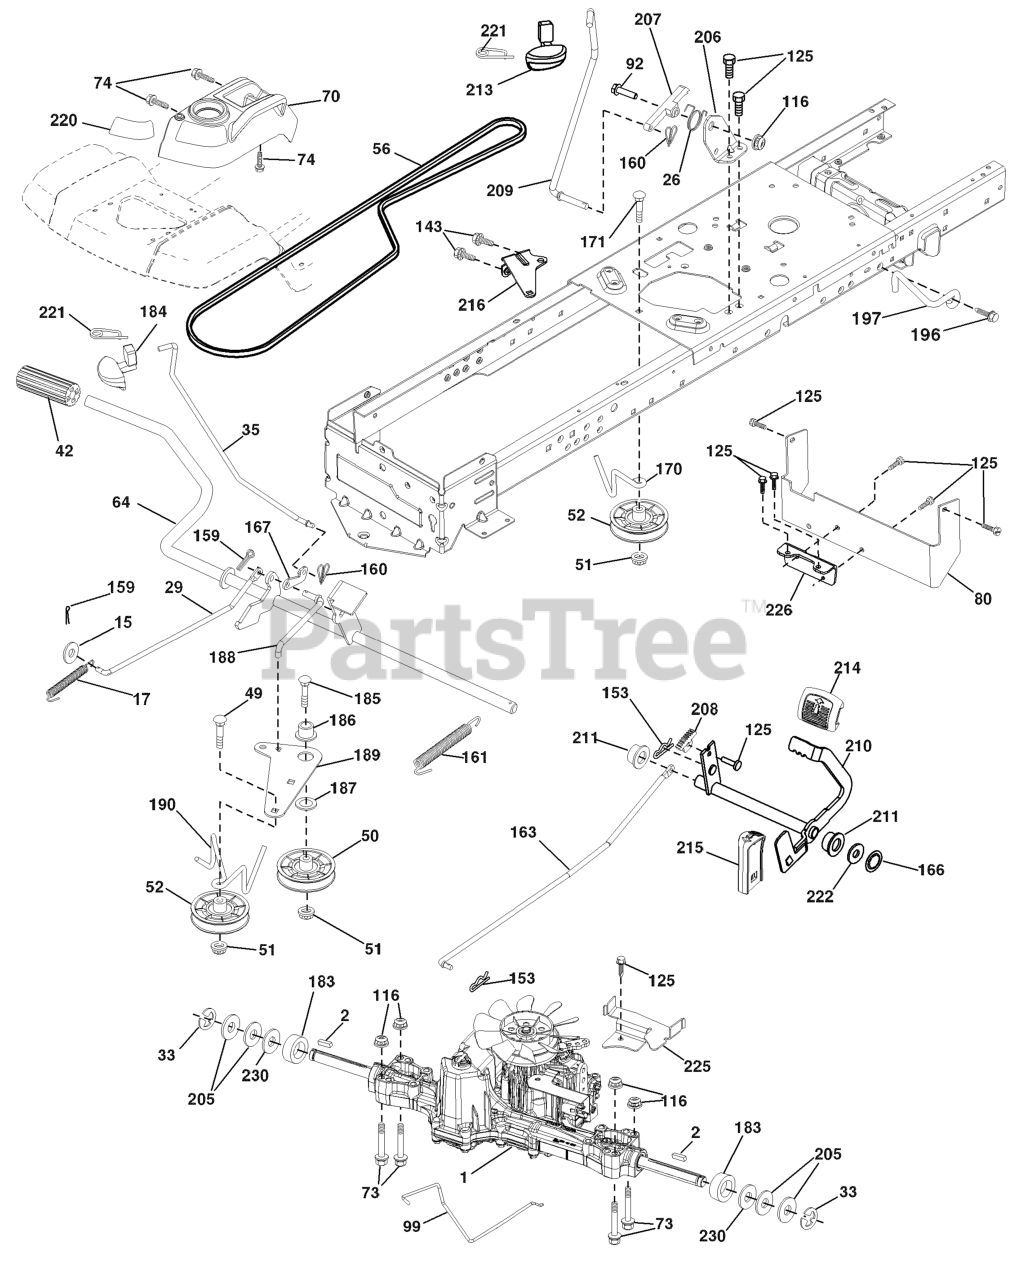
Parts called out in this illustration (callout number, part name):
1	TRANSAXLE.K46CR.ETC.20'PCH.TLT
2	SQUARE KEY
15	WASHER
17	SPRING.BRAKE.K46.GREEN
26	SPRING.RETURN.CRUISE
29	ROD.BRAKE.K46
35	ROD.BRAKE.PARKING.GT.H
42	PEDAL COVER T
50	IDLER.FLAT.910.OFFSET
51	NUT LOCK FLG 3/8-16 UNC
52	IDLER.V-GROOVE.910.OFFSET
56	V-BELT.MOWER.92.40.42/K46
64	SHAFT.ASM.PEDAL.BRK.CNTR
70	RP CONSOLE.ASM.PCH.W/TB
73	BOLT HEX 5/16-18 GR 5
74	SCREW.HI-LO.CONSOLE
80	STRAP TORQUE.ASM.K46/18"TEX
92	BOLT
99	ROD.SPRING.BYPASS.K46.LT.Z
116	NUT LOCK HEX FLANGE 5/16-18
125	SCREW
143	Screw 5/16-18 x 1/2
153	RETAINER M
159	COTTER PIN
160	RETAINER CLIP
161	Spring, Return, Clutch
163	ROD.CONTROL.PEDAL.K46
166	NUT.PUSH.625.2006
167	LATCH.BRAKE.SPRING
170	KEEPER.V-IDLER.CENTER.
171	BOLT
183	SPACER AXLE
184	HANDLE.PARKG.BRK.HUSQ X667
185	BOLT
186	SPACER.RETAINER
187	WASHER 12/32X2X10GA
188	RP.LINK.CLUTCH.GROUND.DRIVE
189	BELLCRANK.GROUND.DRIVE.TEX.
190	KEEPER.BELLCRANK.DRIVE
196	SCREW 3/8-16X1
197	LINK.CLUTCH.ANIT-ROTAT
206	BRKT.MOUNT.LATCH.CRUIS
207	LATCH.CONTROL.CRUISE
208	GEAR.SECTOR.CONTROL.CR
209	ROD.CONTROL.CRUISE.GT.
210	ROCKER.ASM.PEDAL.CONTR
211	BEARING.NYLON
213	KNOB.CONTROL.CRUSIE.HU
214	PEDAL.FORWARD.HUSQVARNA.DEALER
215	PEDAL.REVERSE.TEX.GT.4
216	BRACKET.PULLEY.IDLER.W/TEX
220	REFLECTOR.RH.TEX GT
221	RETAINER.SPRING.CLIP.H
222	WASHER 21/32 X 1-1/4 X 10 GA.
225	KEEPER.BELT.TRANSAXLE.K46
226	BRACKET.MOUNT.TORQUE.K46.TLT
230	WASHER.HARDENED
